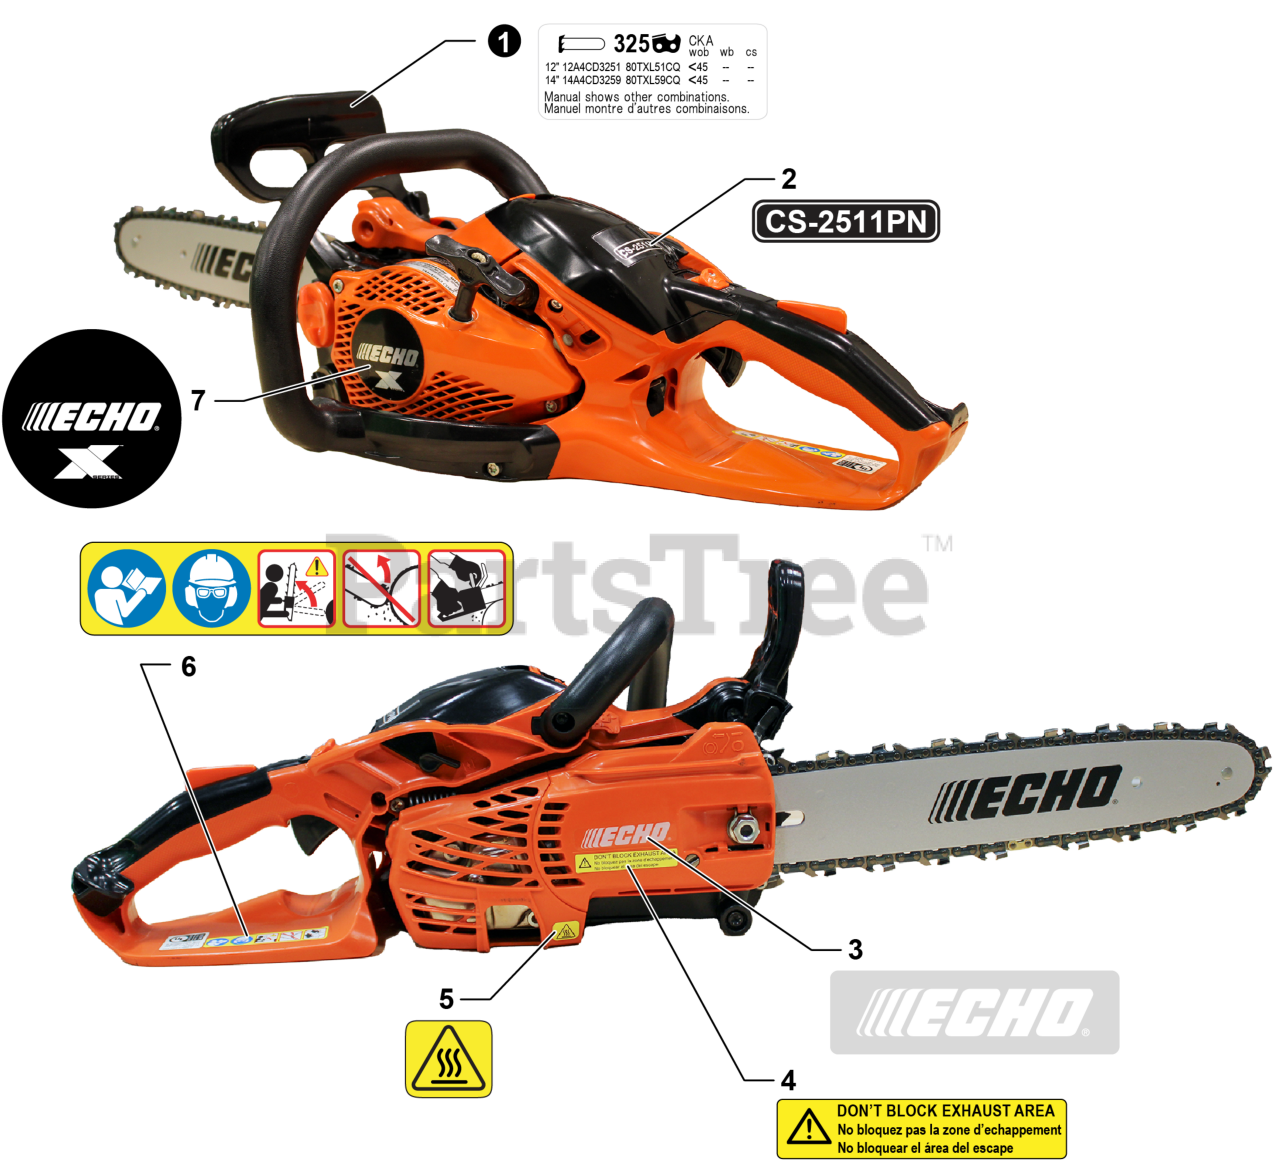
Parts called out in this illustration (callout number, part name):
1	LABEL - BAR & CHAIN
2	LABEL - CS-2511PN
3	LABEL - ECHO
4	LABEL - CAUTION - DON'T BLOCK EXHAUST AREA
5	LABEL - CAUTION - HOT
6	LABEL - CAUTION
7	LABEL - ECHO
